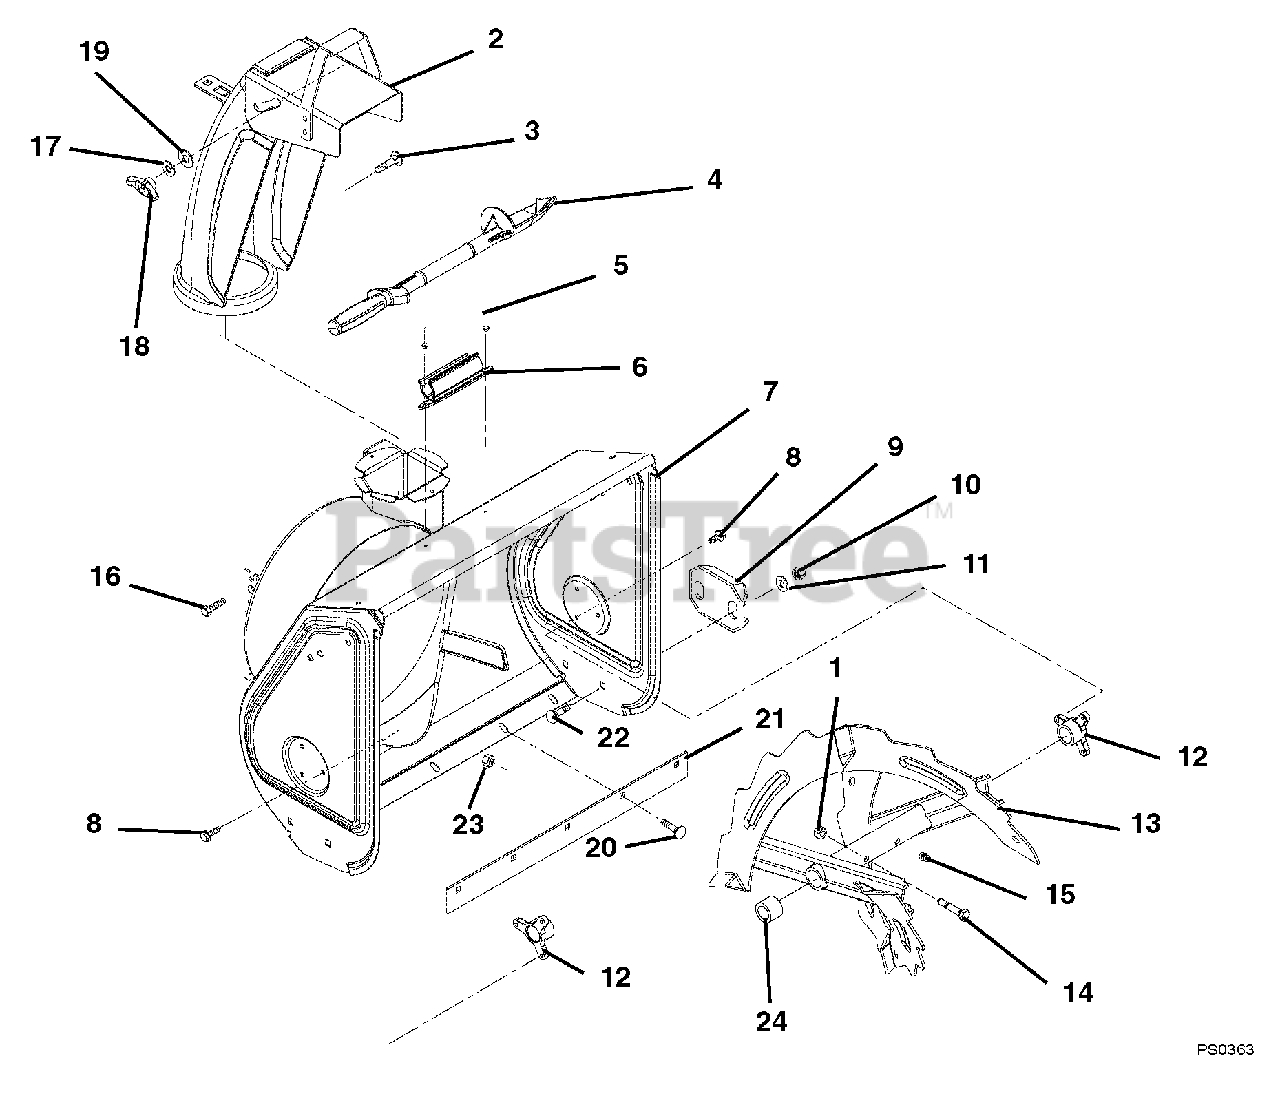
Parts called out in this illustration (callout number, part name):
1	@NUT-LK-CTR .25-20 YWZC
2	CHUTE, DISCHARGE W/CAP & DECAL
3	@BLT-RHDSSQNK .31-18X1.00 G5YZ
4	DEVICE, SNOW CLEAN OUT
5	RVT-POP .187 YZ
6	MOUNT, SNOW CLEAN OUT
7	BLOWER HOUSING W/DECAL 22" ST
8	SCR-TAP .25-20X.50 HWH TR YWZ
9	SKID SHOE, REVERSIBLE - BLACK
10	@NUT-LK-CTR .38-16 YWZC
11	@WSHR-FL-STL.38X.875X.083 YWZC
12	BUSHING, RAKE SHAFT .75"
13	AUGER, 20" RH, BLK SERR W/ZERK
13	AUGER, LH 20", BLK SERR W/ZERK
14	SHEAR BOLT WITH NUT
15	ZERK,FITTING .25X.125 DRIVE IN
16	@SCR-TAP .31-18X.50 HWH TR YWZ
17	@WSHR-FL-STL.344X.688X.065YWZC
18	KNOB,WING .31-18 UNC NYL/TALC
19	WSHR-FL-NY .375X.75X.060
20	BLT,RDSHHDSQSHNK .31-18X.62 YZ
21	SCRAPER BLADE, 22" COMPACT HI
22	@BLT-RHDSSQNK .38-16X.75 G5YZ
23	@NUT-LK-TOP-FLG .31-18 YWZC
24	BSHG-SLV .75X1.12X1.062 NYL BK
